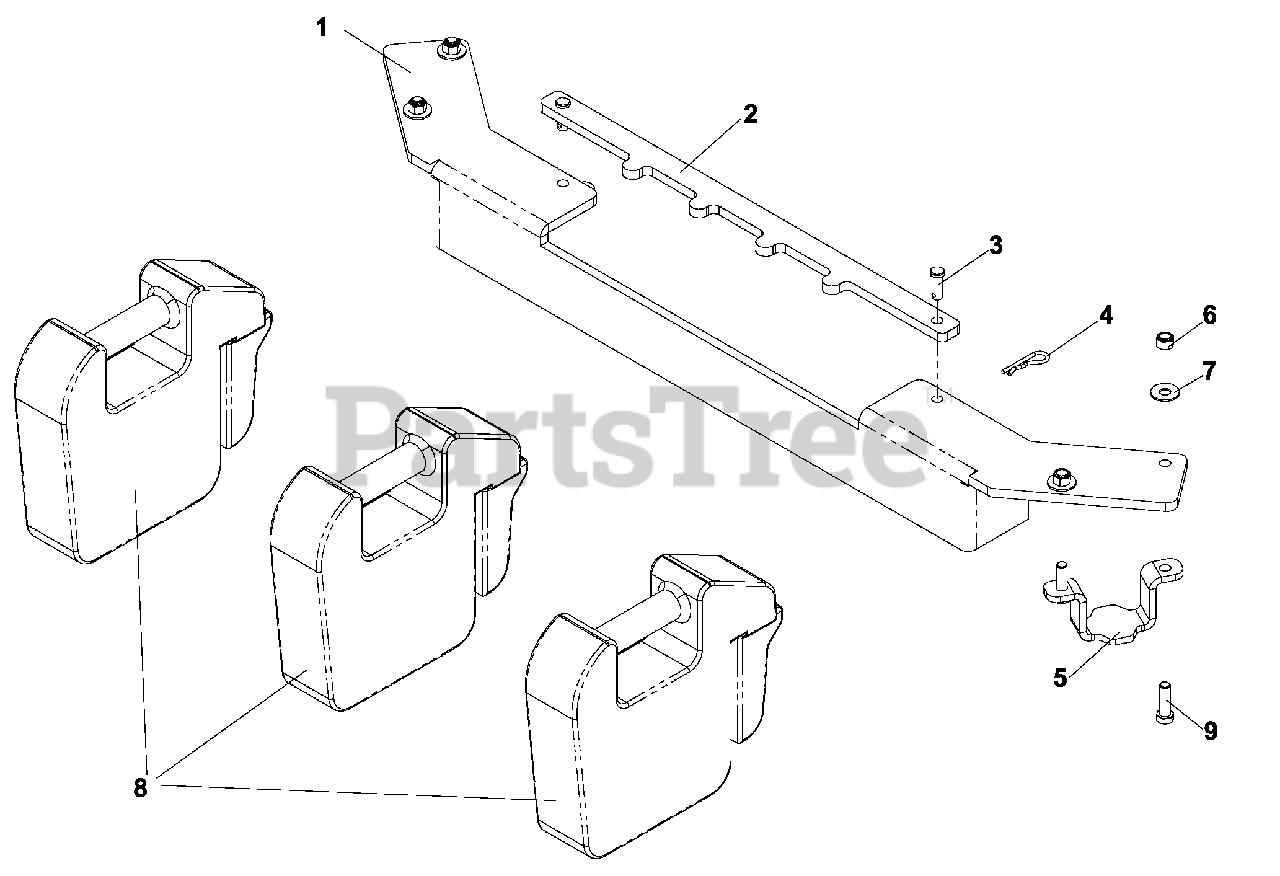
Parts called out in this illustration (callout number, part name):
1	WEIGHT BAR, FRONT
2	HOLD DOWN, WEIGHT BAR
3	CLEVIS PIN
4	SPRING RETAINER
5	WEIGHT KEEPER
6	NUT, 3/8, NYLOC
7	WASHER, 3/8
8	CAST COUNTERWEIGHT
9	HCS, 3/8-16 X 1 1/4, GR5
